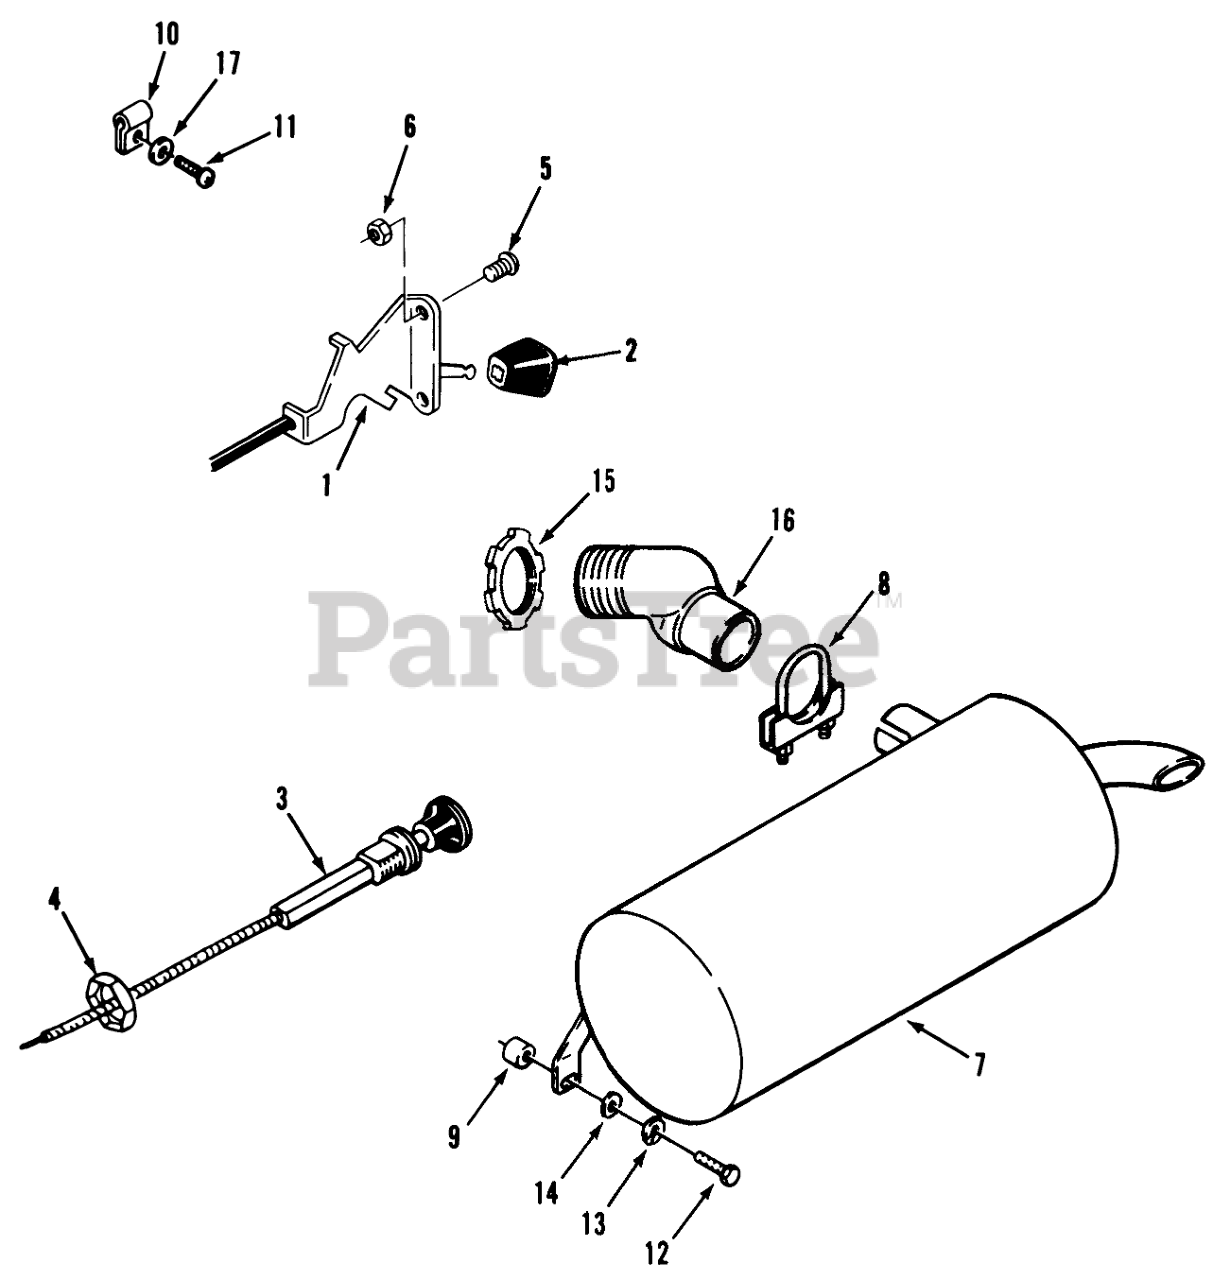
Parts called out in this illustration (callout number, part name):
1	CONTROL-THROTTLE
2	KNOB-CONTROL
3	CONTROL CHOKE
4	NUT-HEX PALNUT
5	SCRW-PHC
6	Nut
7	Muffler
8	CLAMP-1 1/2
9	SPACER
11	Screw
12	Bolt
13	Lockwasher
14	WASHER 5/16 SAE
15	Nut-Lock
16	Elbow
17	Washer
